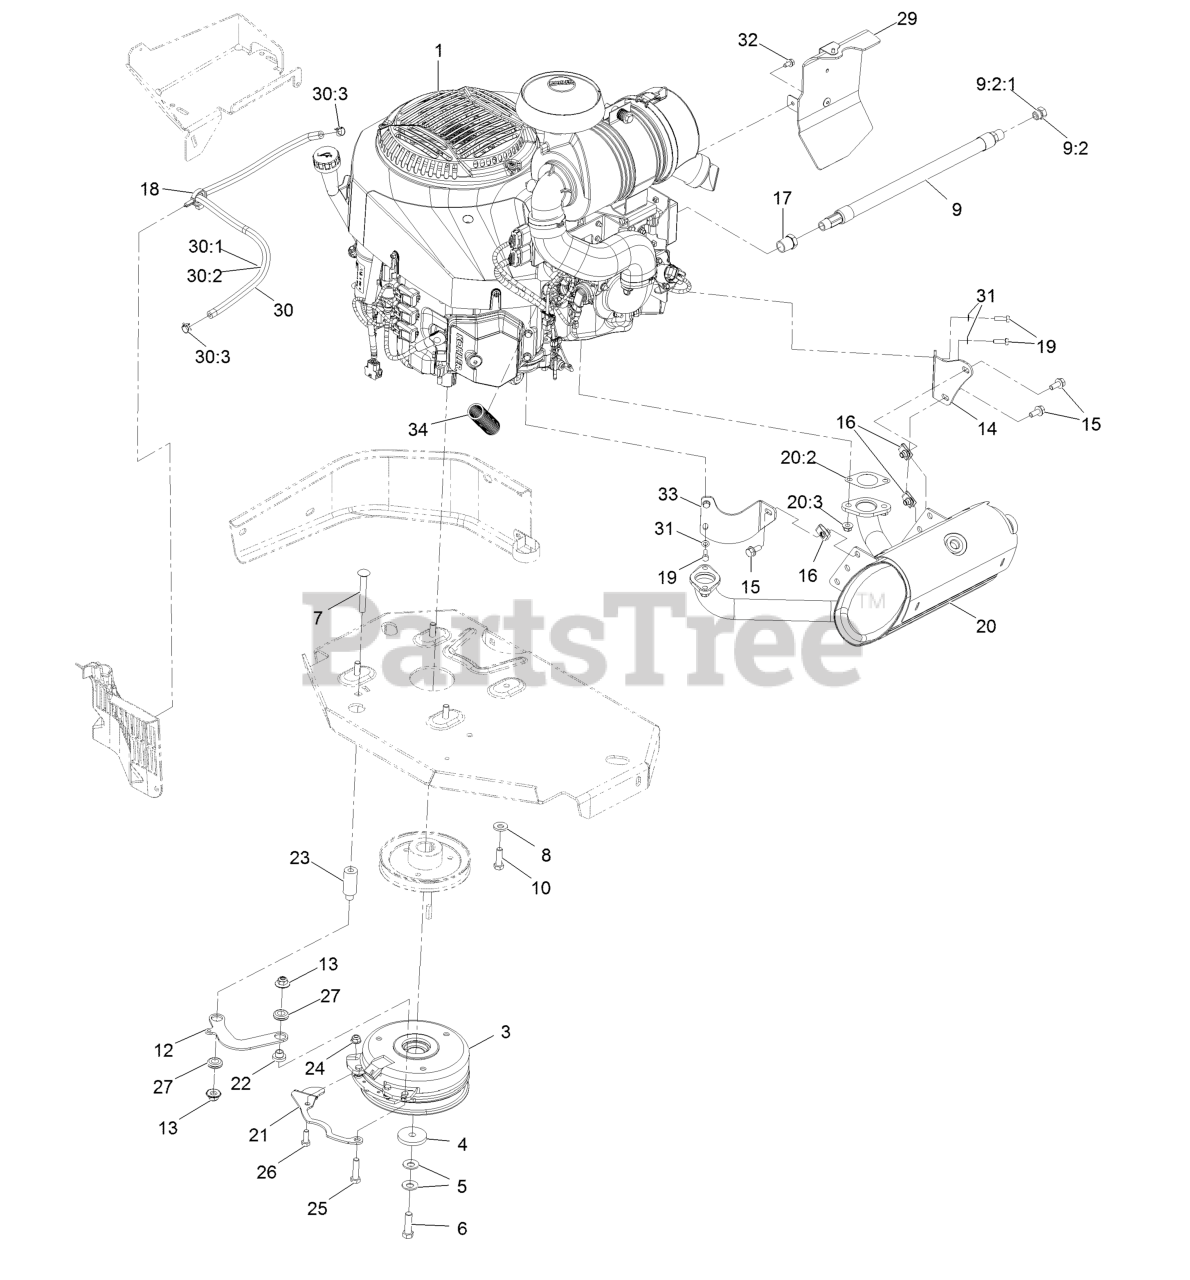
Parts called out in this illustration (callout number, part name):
3	Clutch, Cms250
3	Clutch Kit
4	Washer-Clutch
5	Washer-Spring Disc 7/16
6	Screw-HH 7/16-20 X 1 1/2 W/Loctite
7	Bolt-Carriage 3/8-16 X 3
8	Washer-Spring Disc 3/8
9	Oil Drain Hose ASM
9:2	Plug-W/O-Ring
9:2:1	O-Ring
10	Screw-HH 3/8-16 X 1 1/4
12	Link-Anchor, Clutch
13	Nut-Nyloc 3/8-16 Flg
14	Bracket-Muffler
15	Screw-HH Flg 5/16-18 X 3/4
17	Bushing
18	Clamp-Hose
19	Screw-HH M6-1 X 20Mm W/Patch
20	Muffler-940-980 Koh Efi
20	Muffler Kit
20:2	Gasket-Exhaust
20:3	Nut-Flange, Lock
21	Belt-Guide
24	Nut-Nyloc 5/16-18 Flg
25	Screw-HH 3/8-16 X 1 1/2
26	Screw-HH 5/16-18 X 7/8
27	Grommet-Rubber
29	Rear Baffle ASM
30	Fuel Line ASM
30:1	Hose-Fuel Line 29"
30:2	Sleeve, Thermal
30:3	Clamp-Hose
31	Washer-Spring Disc 1/4
32	Screw-HWH M6-1 X 12Mm Tf
33	Bracket-Muffler, Front
34	Conduit-Convoluted
